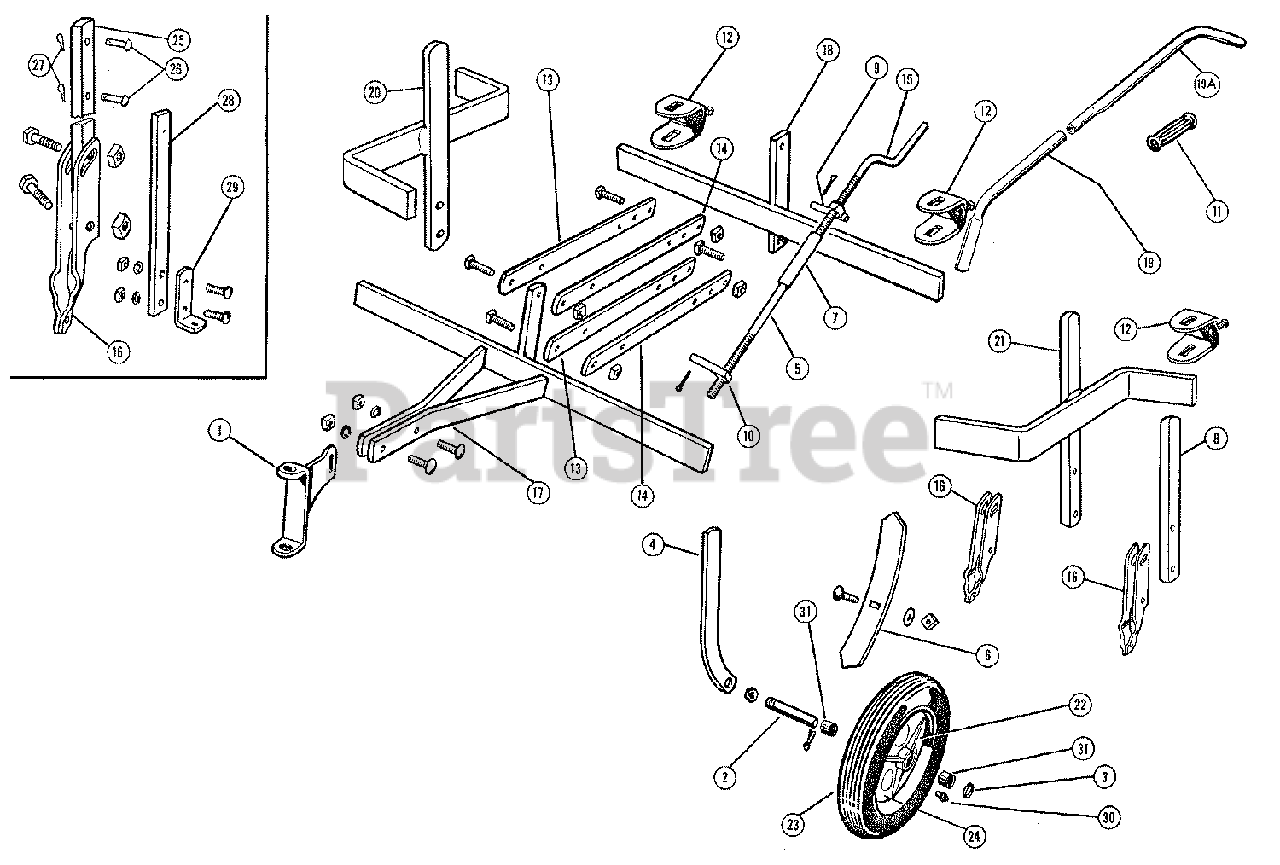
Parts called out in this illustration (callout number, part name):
1	DRAW BAR END
2	GUAGE WHEEL SPINDLE
3	GUAGE WHEEL WASHER
4	GUAE WHEEL STANDARD
5	LOWER SCREW MEMBER
6	CULTIVATOR STEEL WITH BOLT
7	ADJUSTMENT COUPLING
8	TOOL STANDARD -- SHORT
9	UPPER ADJUSTMENT NUT
10	LOWER ADJUSTMENT NUT
11	HANDLE GRIP
12	SHANK CLAMP
13	PARALLEL BAR (RIGHT) -- Unthreaded
14	PARALLEL BAR (LEFT) -- Threaded
15	UPPER SCREW MEMBER
16	TOOL HOLDER ASSEMBLY
17	DRAW BAR ASSEMBLY
18	TOOL BAR ASSEMBLY
19	HANDLE, Control, Upper
19A	HANDLE, Control, Lower
20	R.H. TOOL FRAM ASSEMBLY
21	L.H. TOOL FRAM ASSEMBLY
22	WHEEL, Complete w/Juvenile Tires 10 x 1.75
23	TIRE - 10 x 1.75
24	WHEEL ONLY
27	SPRING CLIP
28	TOOL STANDARD
29	TOOL HOLDER
30	#1641 GREASE FITTING
31	WHEEL BUSHING
